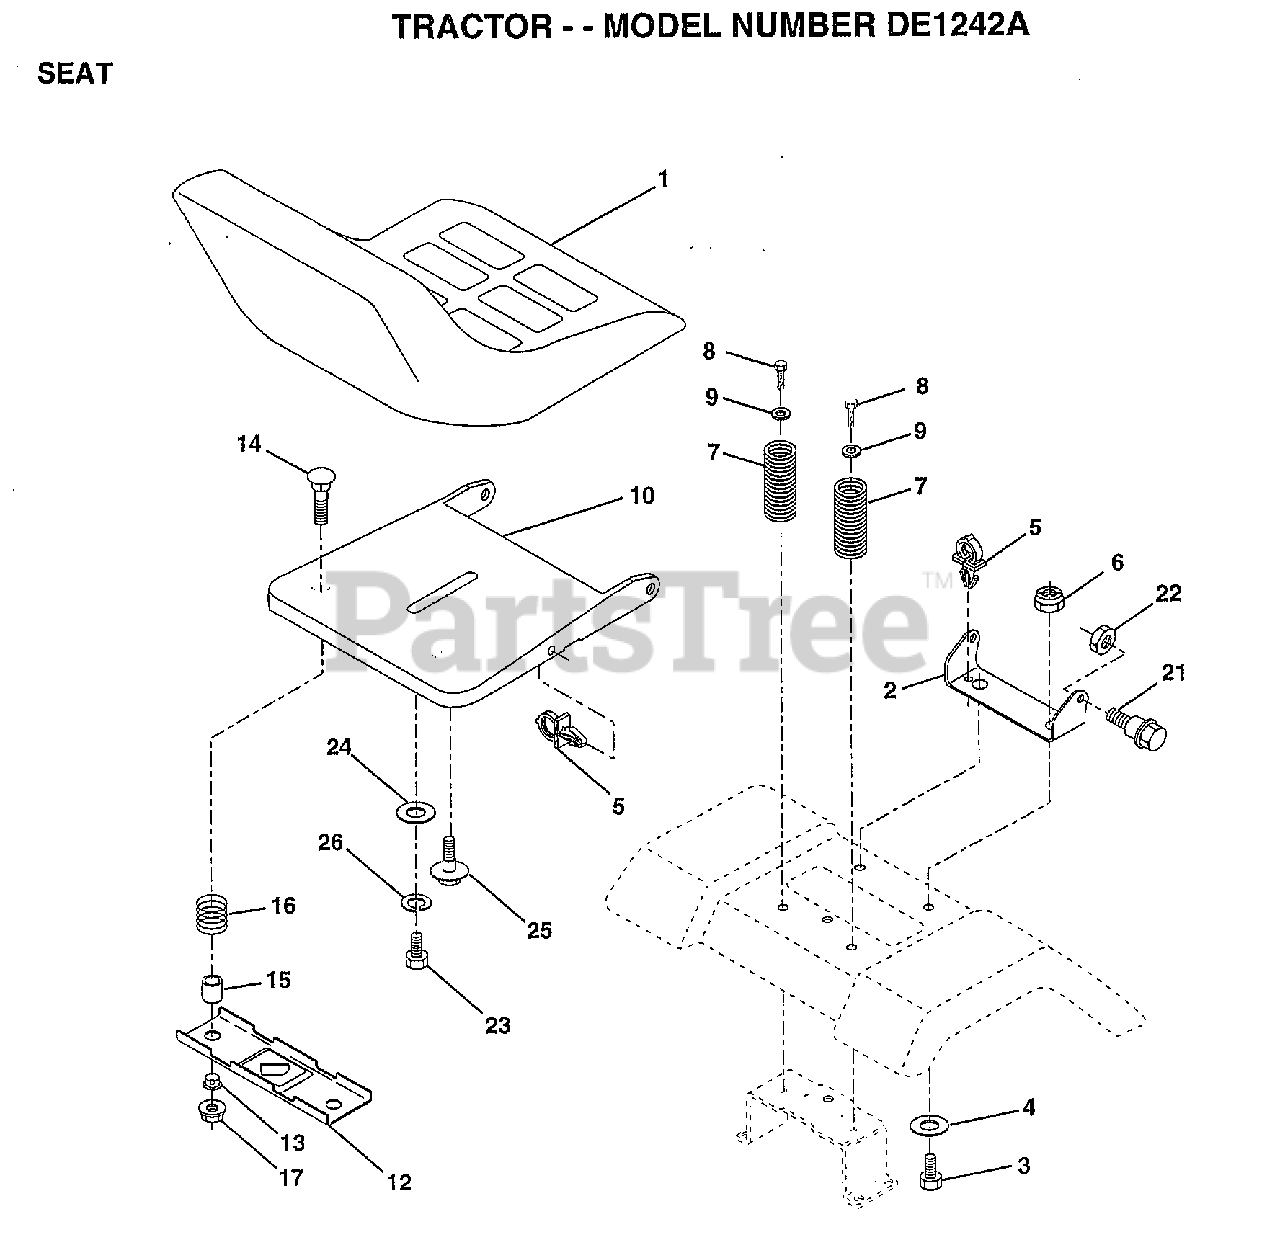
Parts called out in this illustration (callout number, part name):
2	BRACKET PVT SEAT
3	BOLT
4	WASHER PM
5	CLIP.PUSH-IN.HING
6	NUT
7	SPRING COMPRESSIO
8	SCREW GTV
9	WASHER
10	PAN-SEAT
12	BRKT SWITCH
13	BUSHING
14	BOLT-RD HD SQ NK
15	SPLIT SPACER
16	SPRING
21	"BOLT,SHOULDER"
22	NUT
23	BOLT
24	WASHER
25	"BOLT,SHOULDER"
26	LOCKWASHER
